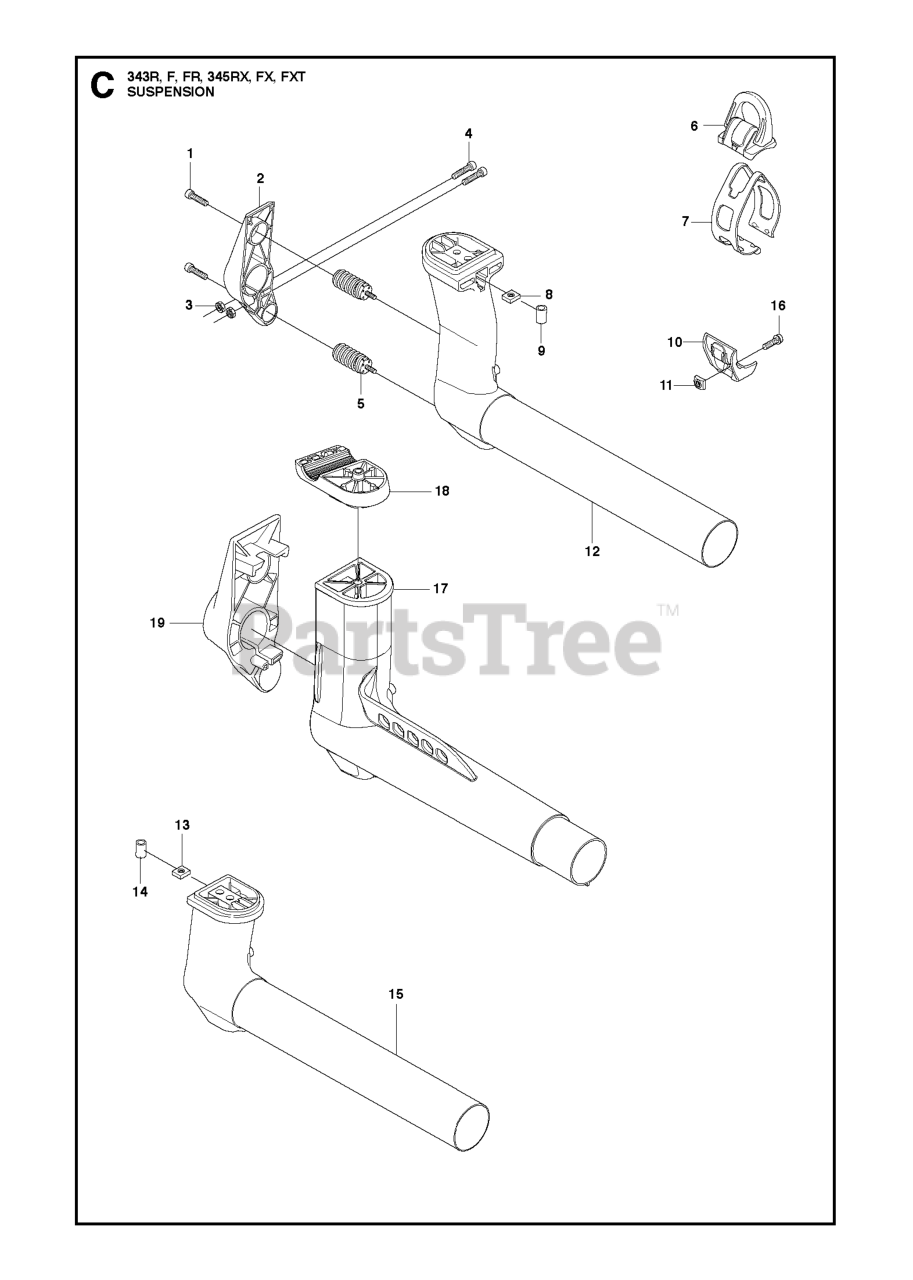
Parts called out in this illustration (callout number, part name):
2	HOLDER
6	LOOP
10	BRACKET, LOWER HANGER
11	SQUARE NUT M5
12	SUPPORT
15	SUPPORT
17	SUSPENSION
18	HANDLEBAR BRACKET
19	HOLDER ANTIVIBRATION
